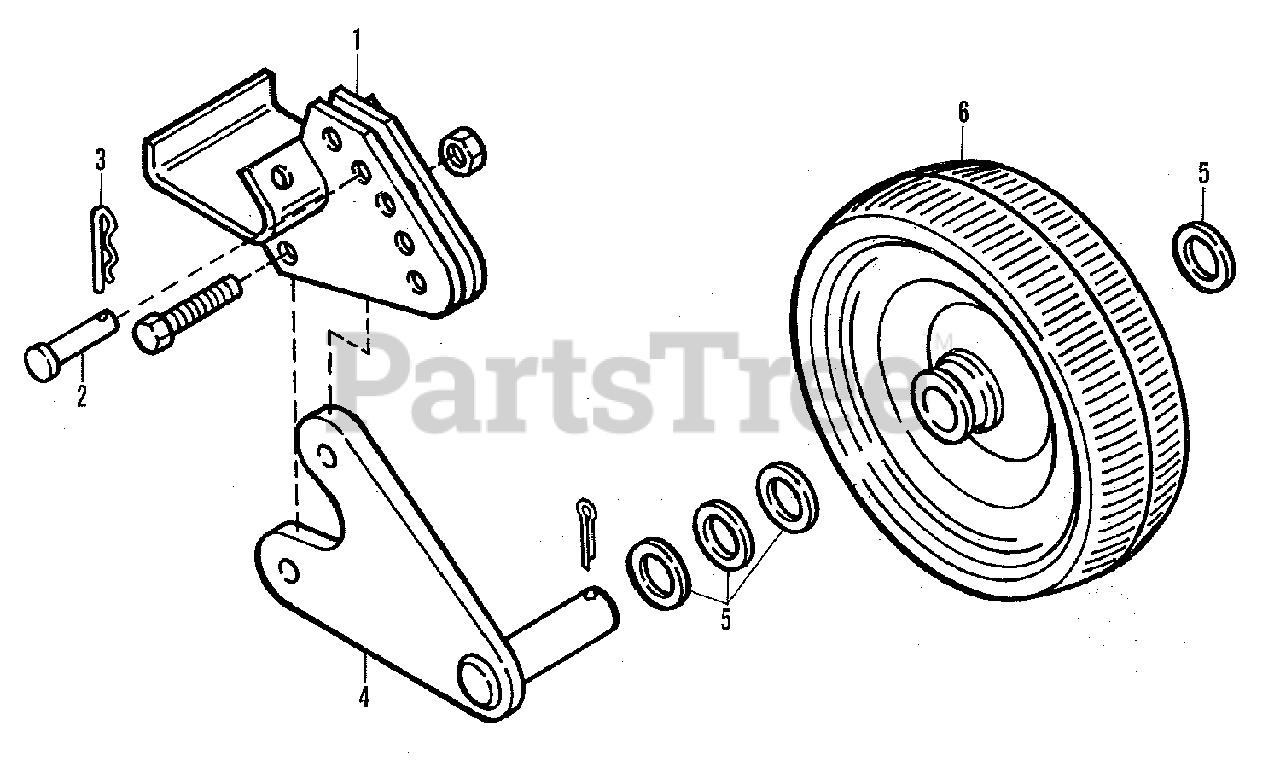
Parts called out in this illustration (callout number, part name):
1	BRACKET, Wheel
1	CAPSCREW, Full Thread, 1/2NC x 1-3/4
1	WASHER, Plain, 1/2 x 1 x 14 Ga.
1	NUT, Jam, 1/2NC
1	NUT, Lock, 1/2NC
2	PIN, Clevis
3	CLIP, Hairpin
4	PIN, Cotter, 3/16 x 2
5	BUSHING, Machinery, 1" x 10 Ga.
6	WHEEL & TIRE ASSEMBLY
